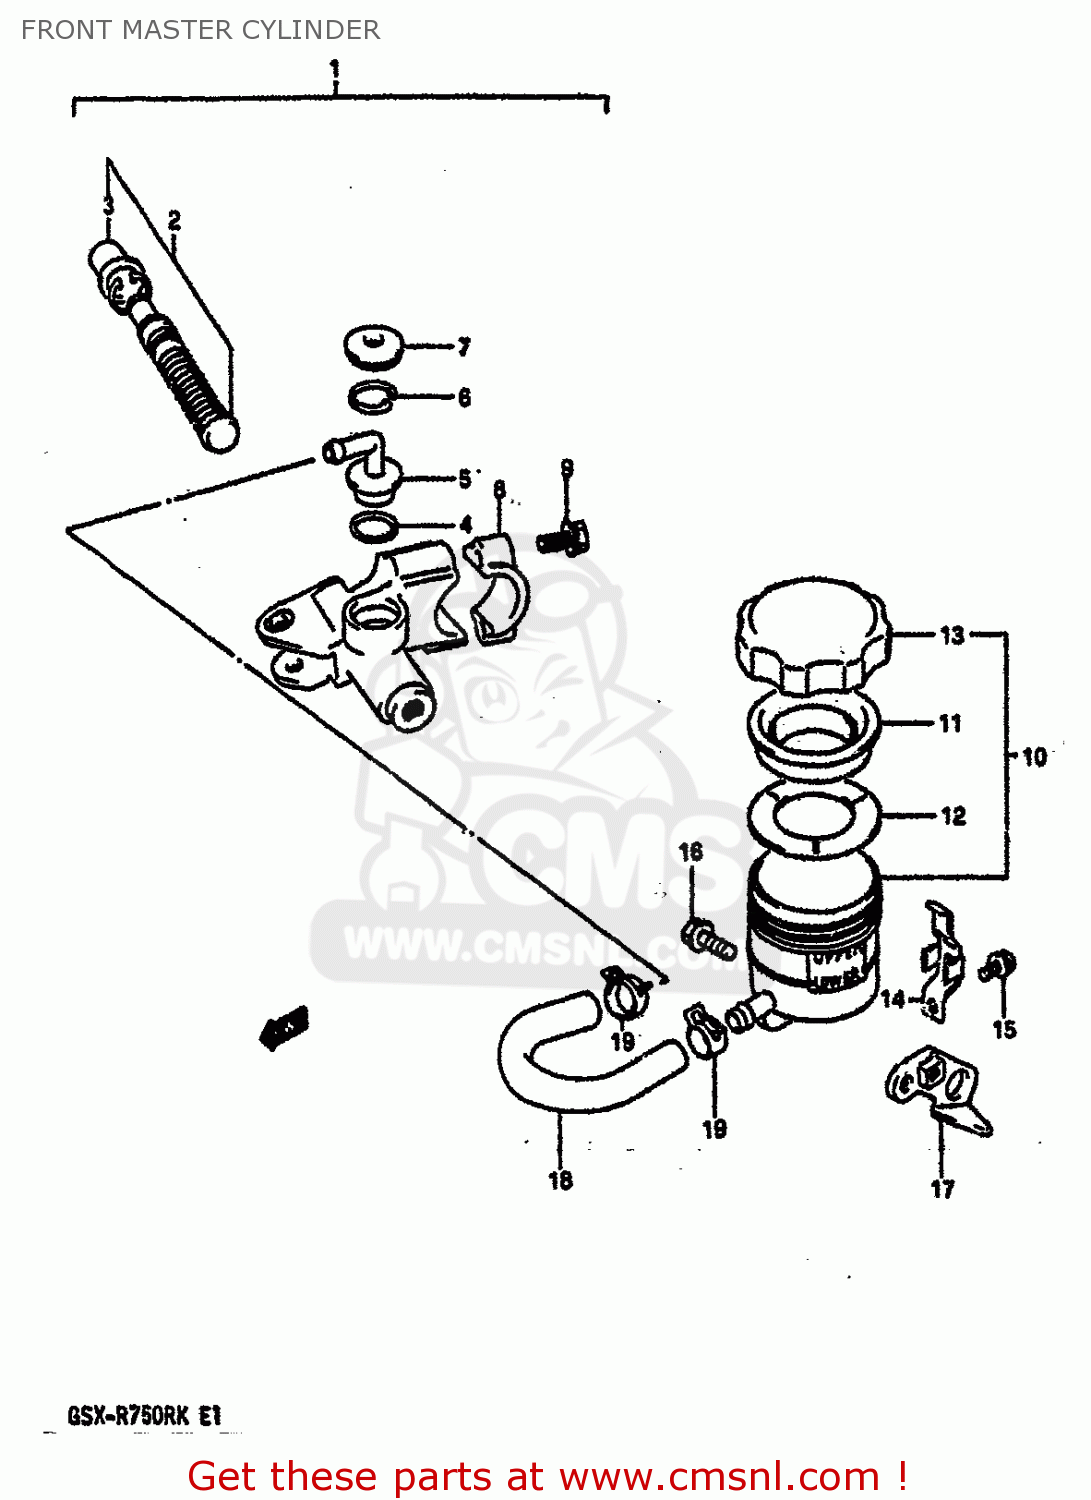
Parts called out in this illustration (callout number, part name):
1	CYLINDER ASSEMBLY,FRONT MASTER
2	PISTON & CUP SET
3	BOOT
4	O RING
5	CONNECTOR
6	CIRCLIP
7	COVER,DUST
8	HOLDER
9	BOLT
10	TANK ASSY,RESERVOIR
11	DIAPHRAGM
12	PLATE,DIAPHRAGM
13	CAP
14	PLATE,RESERVOIR TANK CAP
15	SCREW
16	BOLT 6X16
17	BRACKET COMP,RESERVOIR
18	HOSE,RESERVOIR TANK FR
19	CLAMP,RESERVOIR TANK FR
